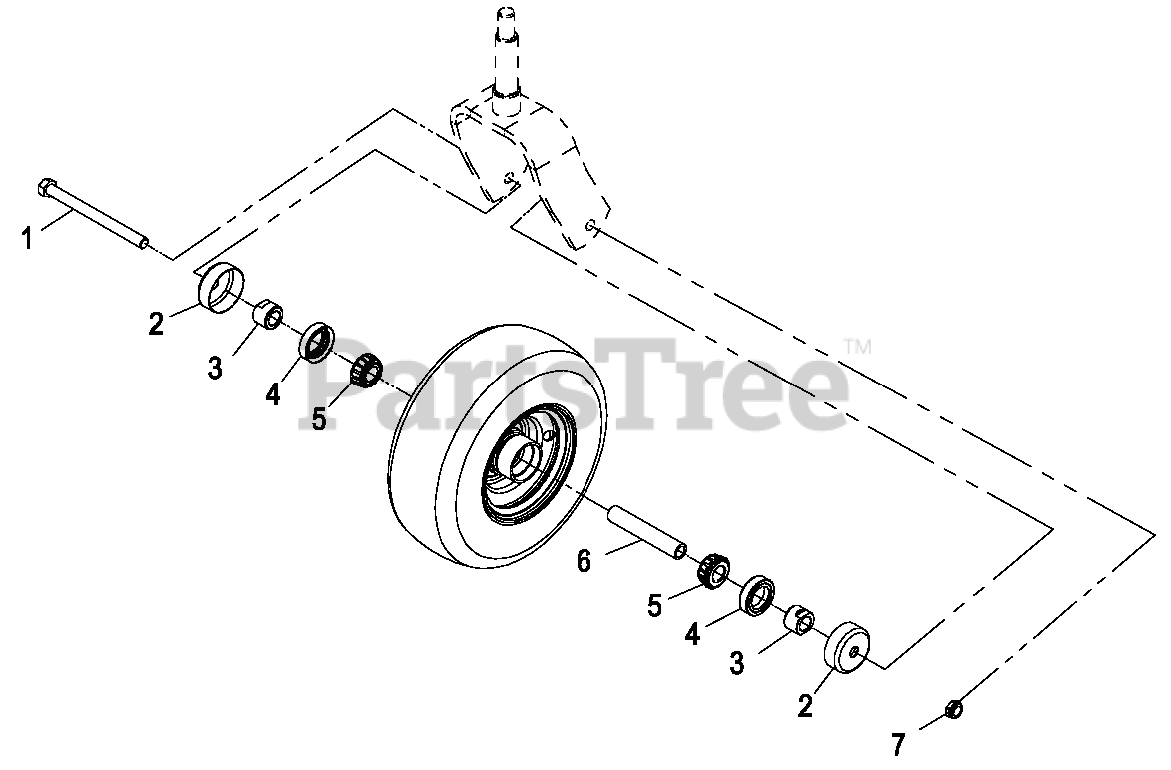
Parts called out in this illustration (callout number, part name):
1	SCREW-HH
2	GUARD-SEAL
3	SPACER-NUT
4	SEAL-CASTER
5	BEARING-CONE, TAPERED ROLLER
7	NUT-HEX
